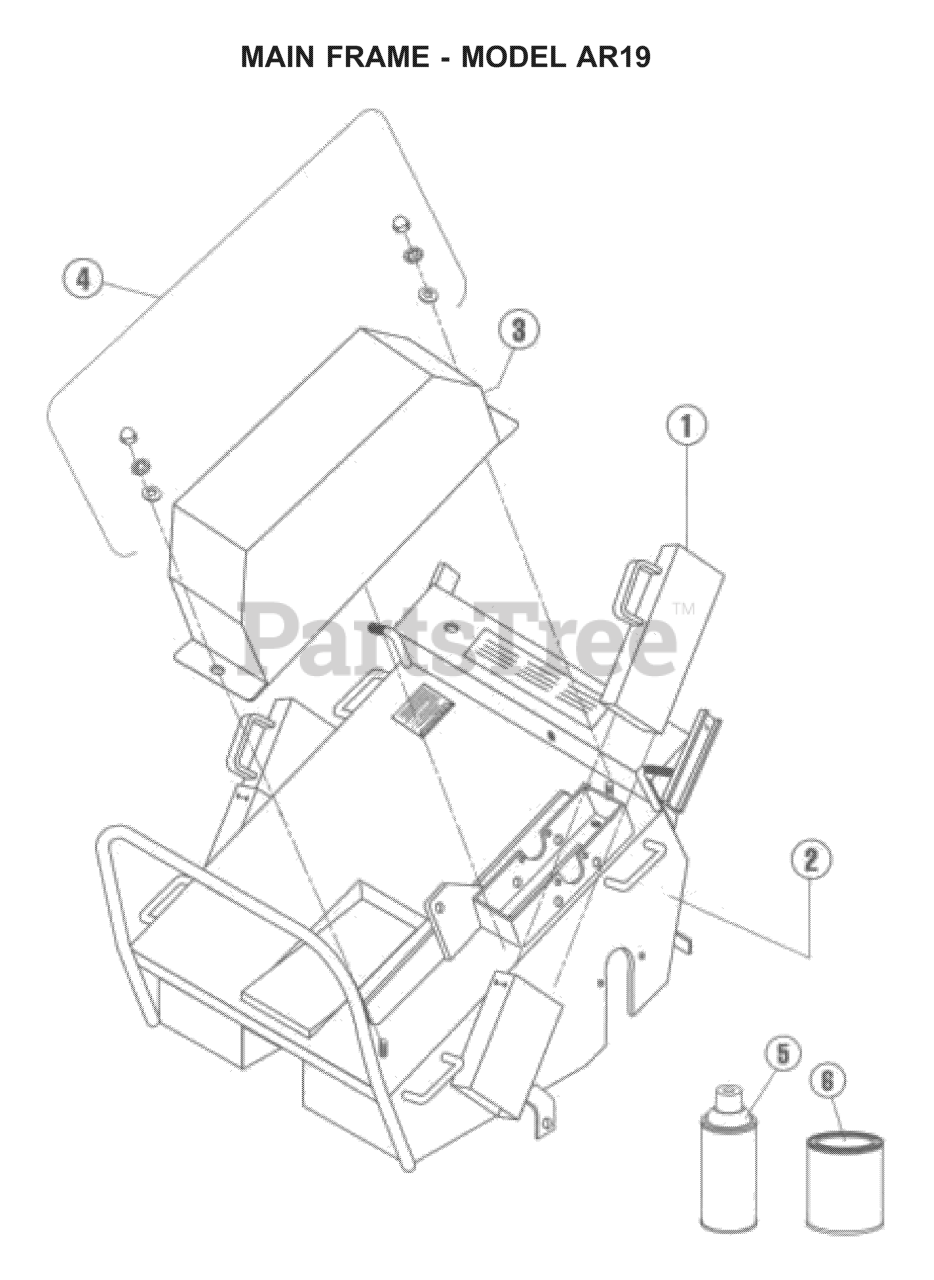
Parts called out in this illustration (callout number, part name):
1	WEIGHT, 36LBS
2	HOUSING W/DECALS ORANGE
3	DRIVE GUARD W/DECALS HUS
4	FASTENER KIT
5	PAINT 12.5 OZ SPRAY ORANGE
